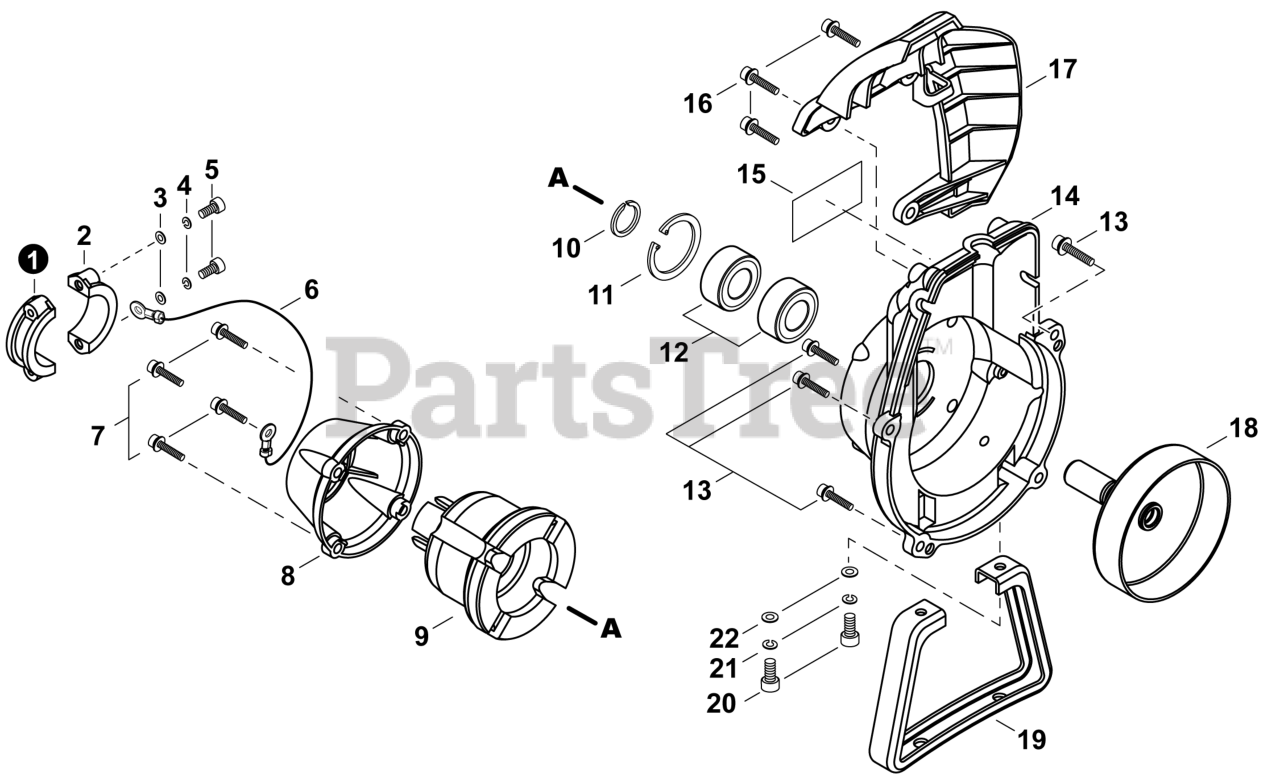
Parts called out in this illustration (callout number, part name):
1	CLAMP - A
2	CLAMP - B
3	WASHER, FLAT 5.5×10×0.8
4	WASHER, SPRING 5
5	BOLT 5×25
6	LEAD - GROUND
7	BOLT 5×20
8	CAP, CUSHION
9	CUSHION, AV
10	RING, SNAP
11	RING, SNAP Ø32
12	BEARING, BALL 6002 DDU
13	BOLT 5×20
14	COVER, FAN
15	LABEL - TRADE
16	BOLT M4×16
17	GUARD, TOP
18	DRUM, CLUTCH
20	BOLT 5×20
21	WASHER, SPRING 5
22	WASHER 5.5×12×0.8
